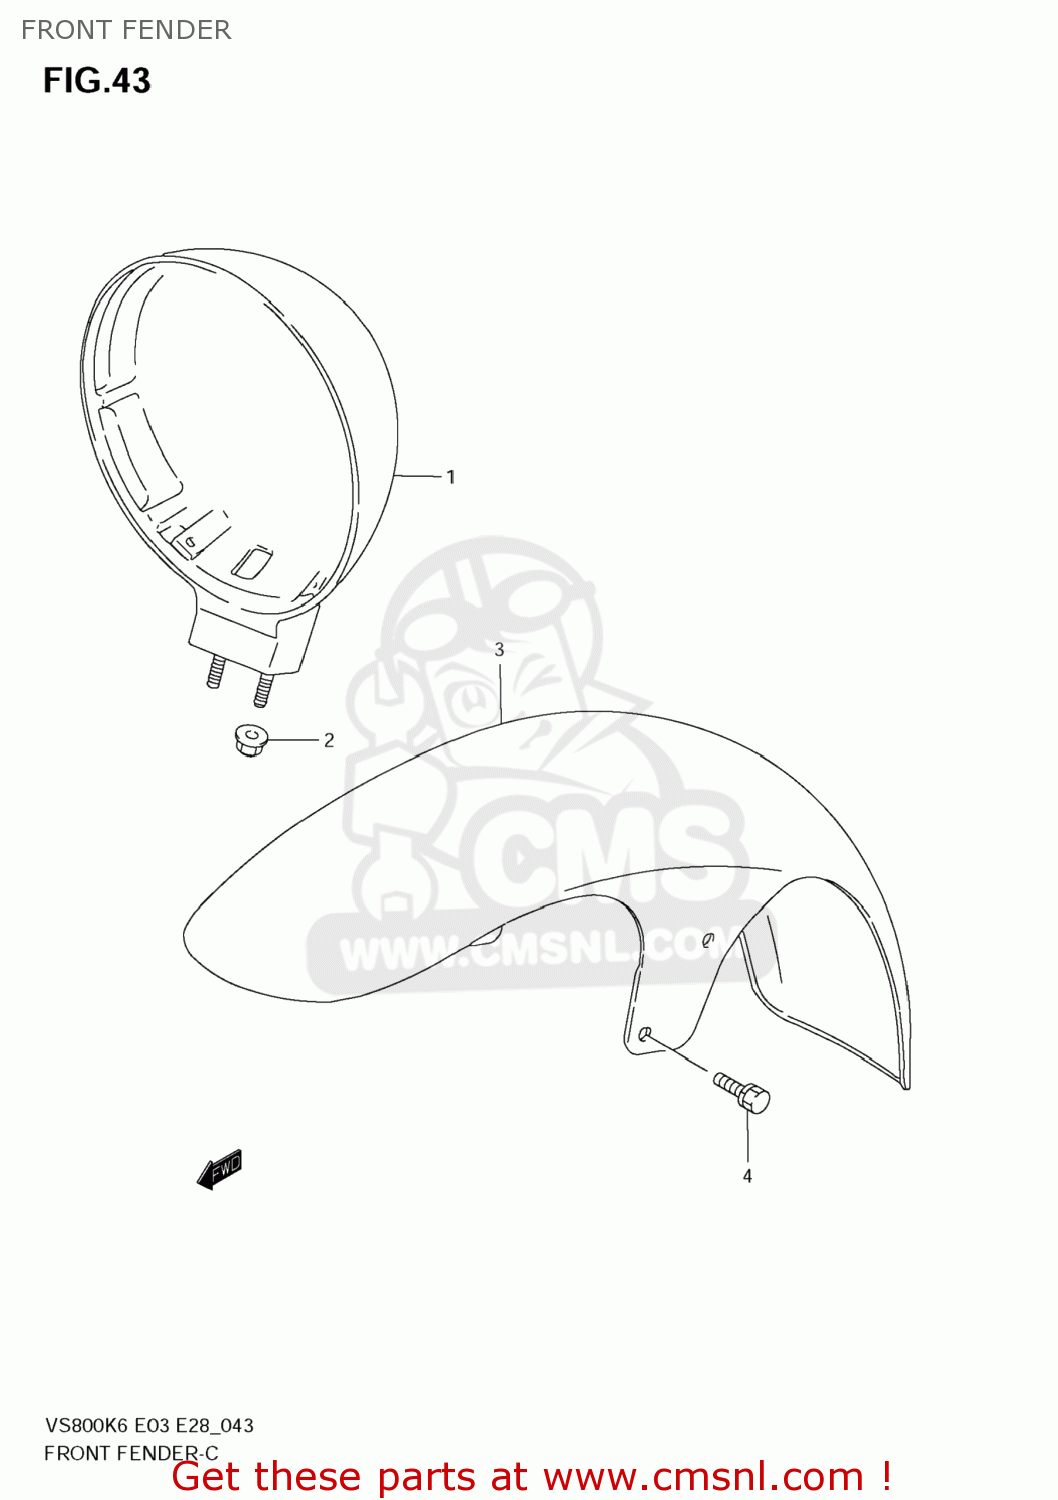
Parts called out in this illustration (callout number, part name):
1	HOUSING,HEADLAMP
2	NUT
3	FENDER,FR
4	BOLT
